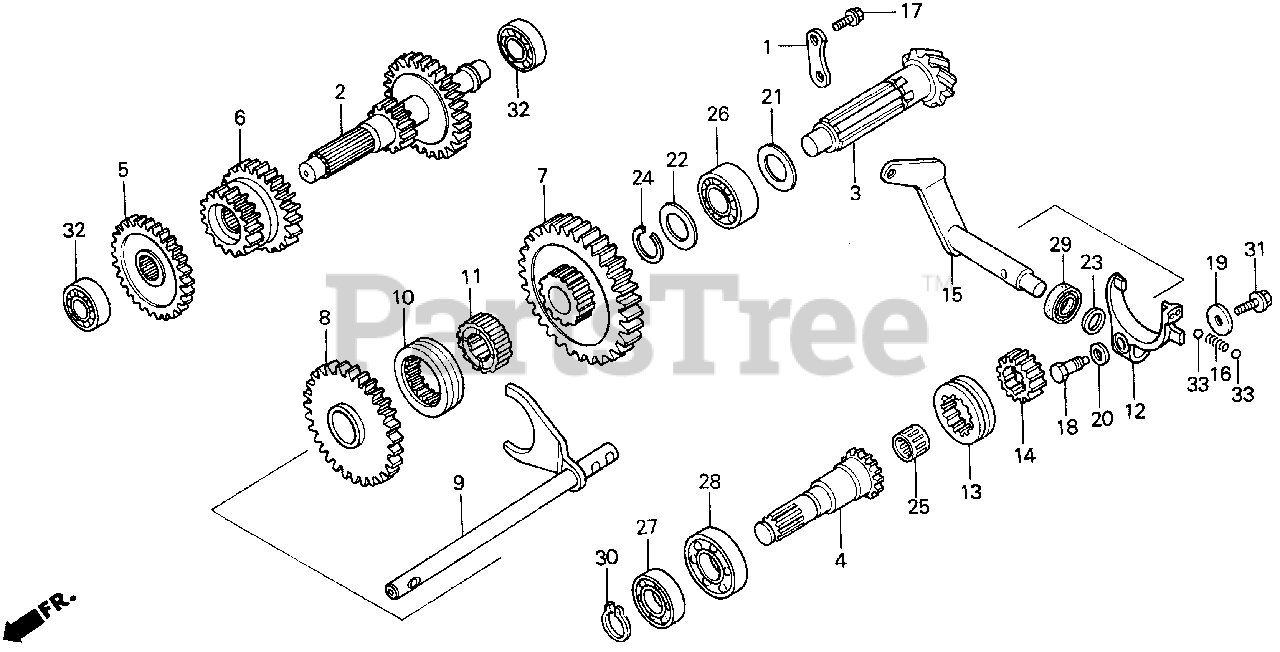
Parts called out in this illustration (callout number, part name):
1	PLATE B, BEARING STOPPER
2	COUNTERSHAFT (LOWER)
3	SHAFT, FINAL
4	SHAFT, FINAL (B)
5	GEAR, COUNTERSHAFT THIRD (39T)
6	GEAR, COUNTERSHAFT FOURTH (29T/17T)
7	GEAR, AUXILIARY LOW DRIVEN (39T)
8	GEAR, AUXILIARY DRIVEN HIGH (35T)
9	FORK, AUXILIARY SHIFT
10	SELECTOR, AUXILIARY
11	HUB, AUXILIARY SELECTOR
12	FORK, SHIFT (2/4WD)
13	SELECTOR, CHANGE (2/4WD)
14	HUB, CHANGE (2/4WD)
15	SHAFT, SHIFT (2/4WD)
16	SPRING, BALL SETTING
17	BOLT, FLANGE (8X20)
18	BOLT, SPECIAL (8X22)
19	WASHER (6X26X3.2)
20	WASHER, CONICAL SPRING (8MM)
21	SHIM (25X38X1.25) (A)
21	SHIM (25X38X1.3) (B)
21	SHIM (25X38X1.4) (D)
21	SHIM (25X38X1.45) (E)
21	SHIM (25X38X1.5) (F)
21	SHIM (25X38X1.55) (G)
21	SHIM (25X38X1.6) (H)
21	SHIM (25X38X1.65) (I)
21	SHIM (25X38X1.7) (J)
21	SHIM (25X38X1.75) (K)
22	SHIM, THRUST (25X38X1.3) (B)
22	SHIM, THRUST (25X38X1.35) (C)
22	SHIM, THRUST (25X38X1.4) (D)
22	SHIM, THRUST (25X38X1.45) (E)
22	SHIM, THRUST (25X38X1.5) (F)
22	SHIM, THRUST (25X38X1.55) (G)
22	SHIM, THRUST (25X38X1.6) (H)
22	SHIM, THRUST (25X38X1.65) (I)
22	SHIM, THRUST (25X38X1.7) (J)
22	SHIM, THRUST (25X38X1.75) (K)
23	WASHER, THRUST (16X24X2)
24	CIRCLIP (OUTER) (25MM)
25	BEARING, NEEDLE (17X21X17)
26	BEARING, RADIAL BALL (25X52X20.6)
27	BEARING, RADIAL BALL (60/22)
27	BEARING, RADIAL BALL (60/22) (TMB)
28	BEARING, RADIAL BALL (60/28)
29	OIL SEAL (16X24X6) (ARAI)
30	CIRCLIP (OUTER) (22MM)
31	BOLT, FLANGE (6X16)
32	BEARING, RADIAL BALL (6203)
33	BALL, STEEL (#10) (5/16)
